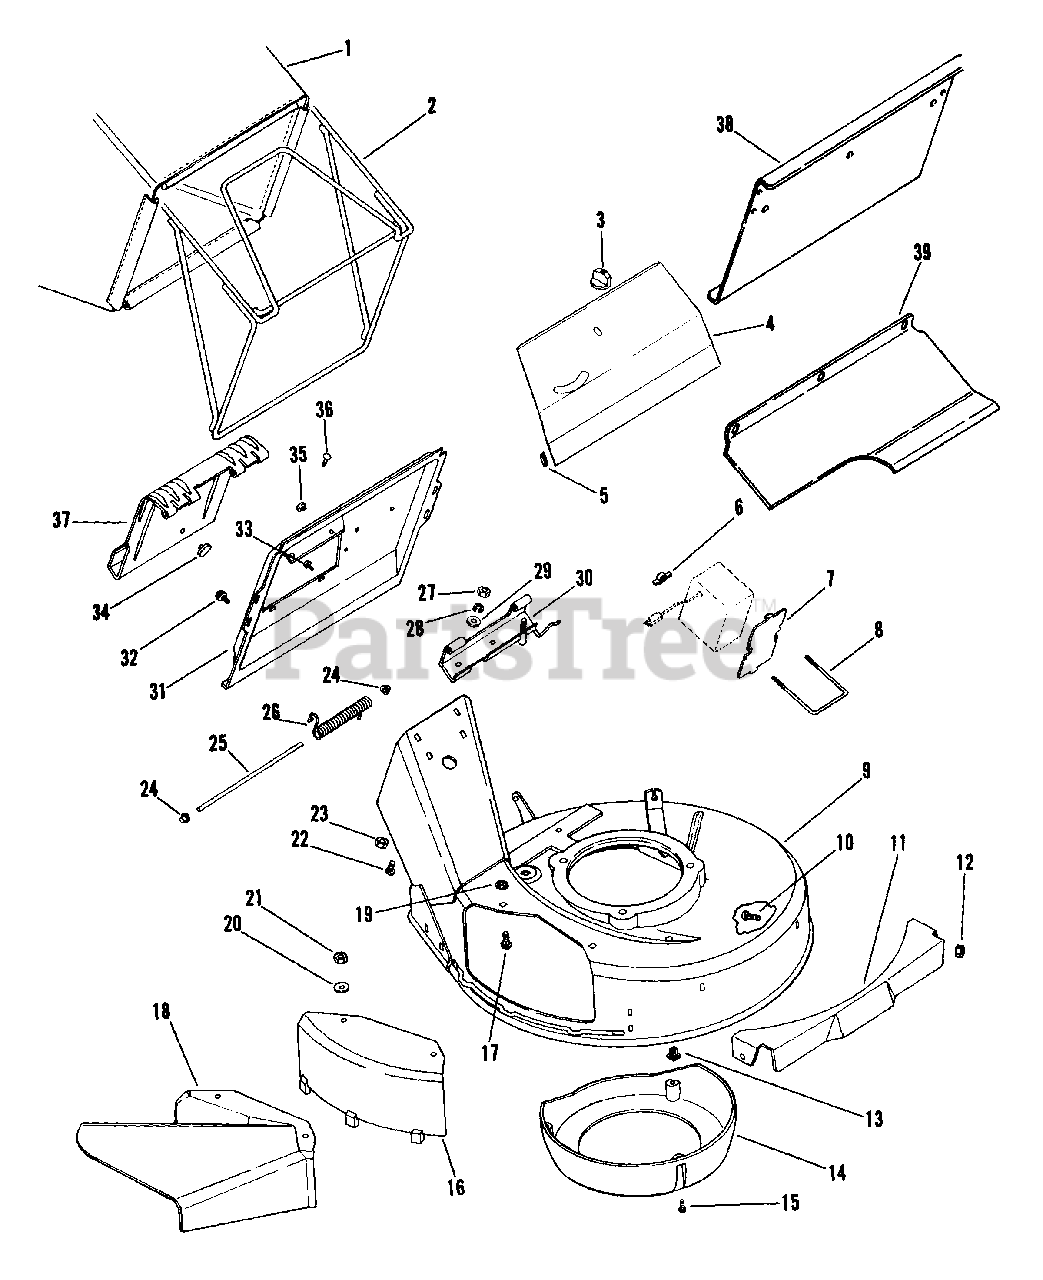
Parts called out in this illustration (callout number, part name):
1	BAG,CONSUMER BLACK 15 OZ/YD2
1	BAG,COMMERCIAL WHITE
2	BAGGER FRAME
3	WING - NUT
4	DRIVE COVER
5	TRIM BUMPER
6	NUT-WING 8-32
7	HOLD DOWN PLATE
8	U-BOLT
9	MOWER PAN W/DECALS
9	MOWER PAN W/DECALS MULCHER
10	BLT-RDHDSQSHNK .31-18X.50 YZ
11	FRONT PANEL
12	NUT-LK .312-18 GR A PL
13	PLASTIC GROMMET
14	CENTER BAFFLE
15	SCR-TAP 10-16X.62 SLPH PL AB
16	SIDE DISCHARGE COVER
17	BLT-RDHDSQNK .31-18X.75 SHT PL
18	DISCHARGE CHUTE
19	NUT-PUSH .312
20	WSHR-FL-STL .38X.875X.083 PL
21	NUT-LK-NYL.312-18 PL
22	BLT-RDHDSQNK .25-20X.62 PL
23	NUT-LK-FLG .250-20 PL
24	PUSH NUT, .25
25	DOOR PIN
26	SG-TORS .120X.68X3.09
27	NUT-HEX .250-20 PL
28	WSHR-LK .250X.077 HVY PL
29	WSHR-FL-STL .380X.875X.179 PL
30	HINGE BASE
30	HINGE BASE WELDMENT
31	CATCHER PLATE
32	SCR-TAP 12-24X.50 HWH PL TR
33	SCR-TAP 10-24X.375 TORX PHD
34	BUTTON BUMPER
36	@BLT-RHDSSQNK .25-20X.38 G2YZ
37	CATCHER PLATE DOOR
38	GUARD PLATE
39	DEFLECTOR BRACE
